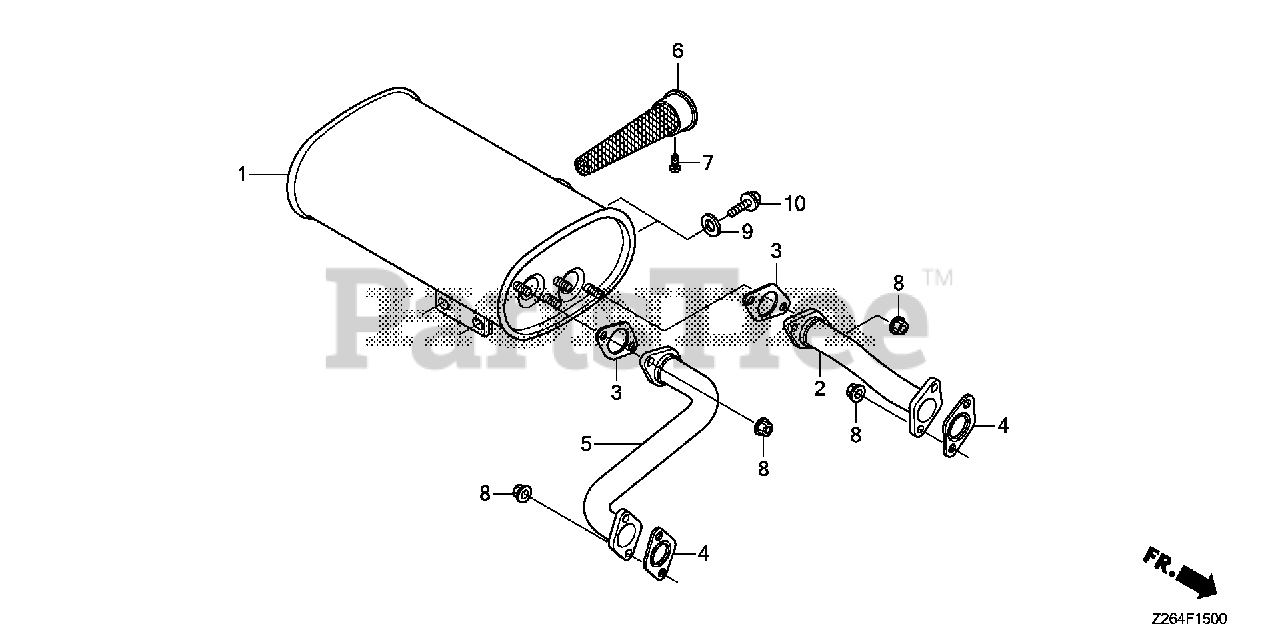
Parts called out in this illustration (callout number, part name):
2	PIPE, R. EX.
3	GASKET, EX. PIPE
4	GASKET, EX. PIPE
5	PIPE, L. EX.
6	ARRESTER, SPARK
7	SCREW, TAPPING (4X8)
8	NUT, FLANGE (8MM)
9	WASHER, PLAIN (8MM)
10	BOLT, FLANGE (8X30)
